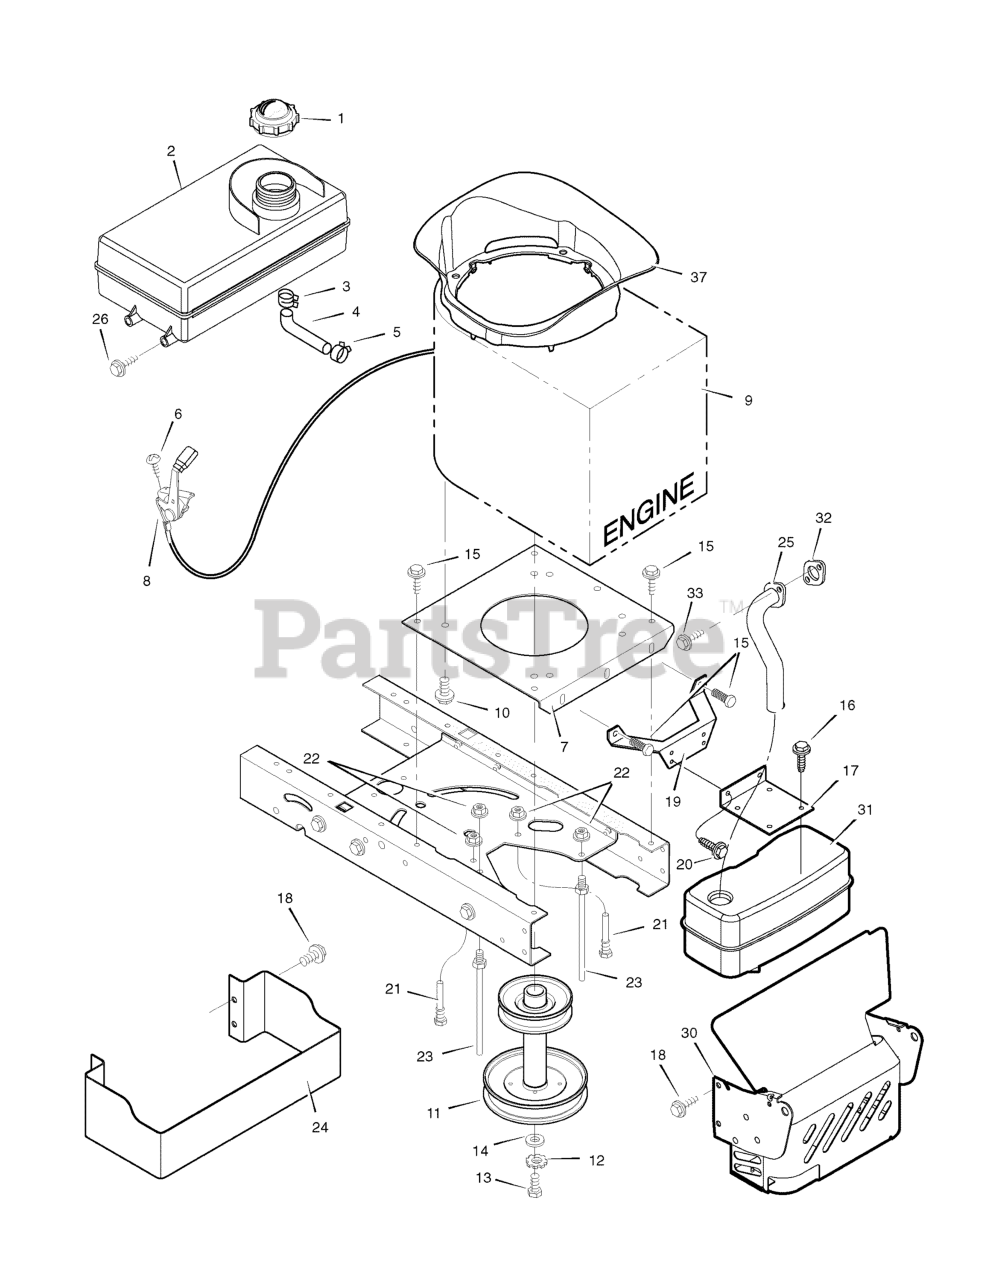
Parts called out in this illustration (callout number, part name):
1	Fuel Cap
2	TANK, Fuel 1.4 Gal.
3	Hose Clamp
4	Fuel Line (Must cut to length)
5	Hose Clamp
7	Plate, Engine
8	Throttle Control
9	Engine, Briggs & Stratton *
10	Bolt, Engine Mount
11	STACK PULLEY ASSEMBLY
12	Lockwasher
13	Bolt, Hex
17	Bracket, Muffler
19	Bracket, Muffler Mount
21	Guide, Belt
22	Nut, Flange
23	Guide, Belt
24	GUARD, Heat Shield
25	Exhaust Tube, Single
30	Shield, Heat
31	Muffler
32	GASKET, Exhaust
33	Screw, Adapter
